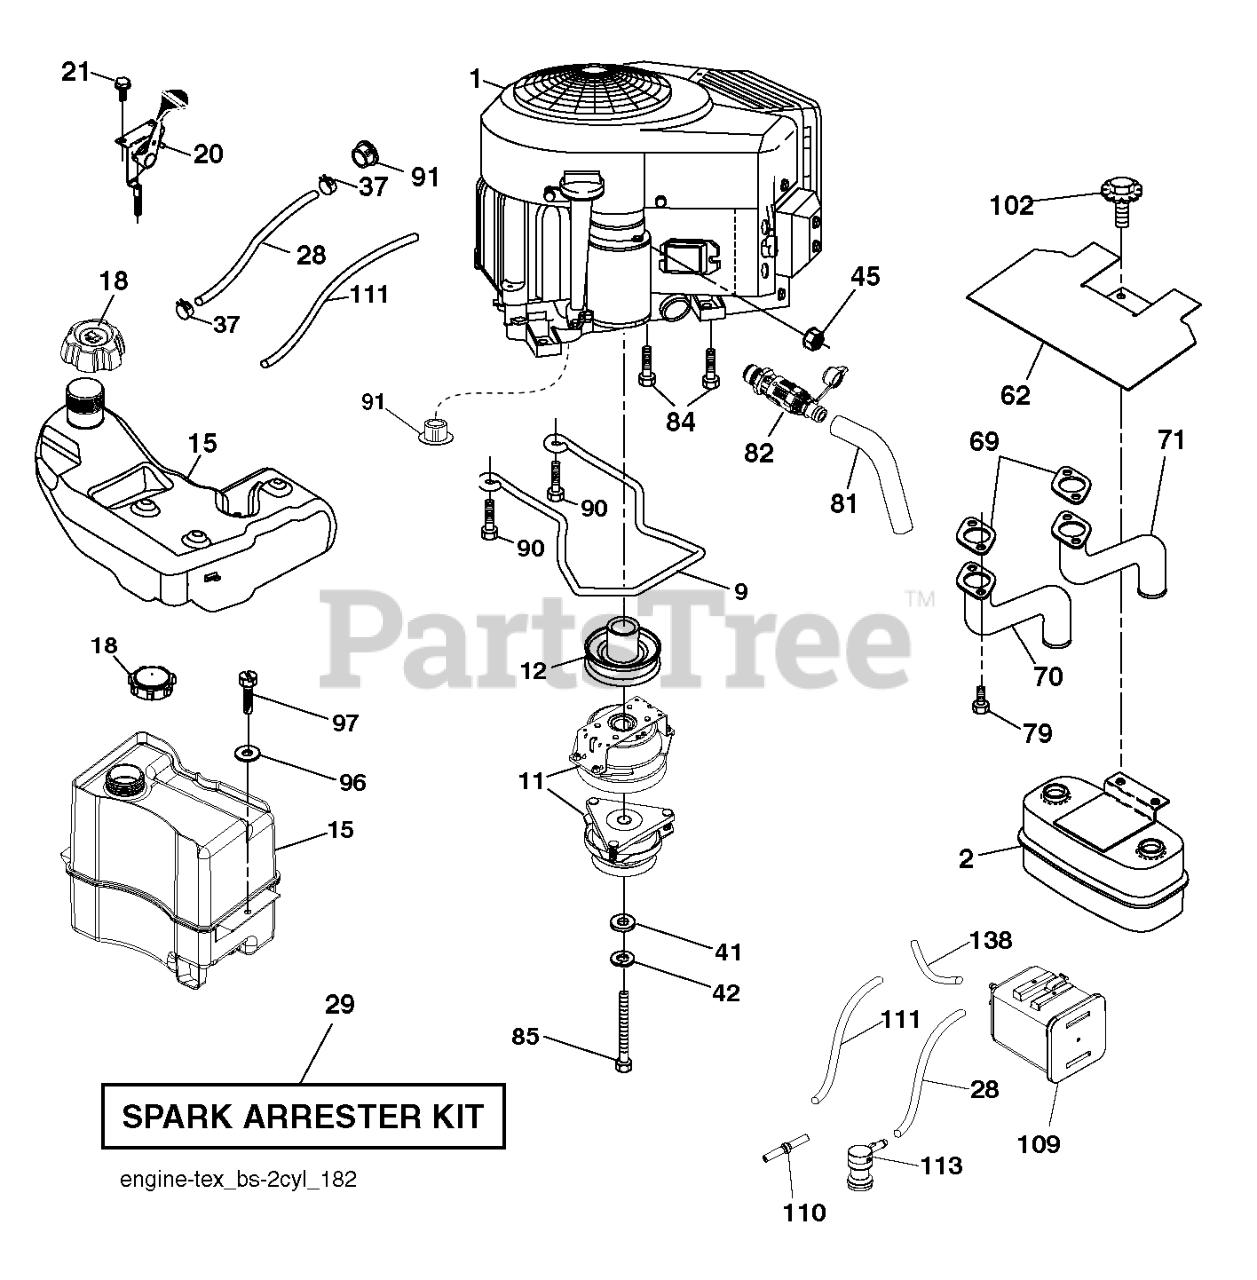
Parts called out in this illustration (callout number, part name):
2	MUFFLER.ASM.TWIN.MNTG.BRACKET
2	MUFFLER.TWIN.CYL.LOW.TONE
9	KEEPER.BELT.ENG.4.25"2.BLT.431
11	CLUTCH.OGURA.5.0PD.GT1.5A-EH07
11	KIT.SVC.CLUTCH.ELECTRIC.
12	PULLEY.ENGINE.TUFFTORQ
15	FUEL TANKS
15	Tanks
15	TANK.ASM.FUEL.3GA.CARB
15	FUEL TANK
18	CAP.ASM.FL.RITCH.3"E10.SYM.498
18	FUEL CAP
18	CAP.2.25'.VENTED.RATCHET.EPA
18	Fuel Caps
18	FUEL.CAP.ASM.2.25TETHRED.RATCH
18	CAP ASM.FUEL.2.25"FR.
18	CAP ASSY FUEL 3" GRAY
20	THROTTLE.COBRA.38"READSTART.BK
20	THROTTLE CABLE
20	CONTROL.TH/CK.COBRA.B&S.TWN.BK
21	SCREW.#10 X 0.750.BOS
28	LINE.FUEL.20"FRONT.EMI
28	LINE.FUEL.64"REAR.EMIS
28	HOSE.1/4".LOW.PERM.FUEL.LN.22"
29	KIT.SPARK ARRESTOR 794945 B&S
37	HOSE CLAMP
42	LOCKWASHER
45	NUT HEX_LRG FLG_1_4-20_LOCK
62	SHIELD.HEAT.MUFFLER
69	GASKET.MUFFLER
70	EXHAUST.TUBE.LH.BS/TWIN
71	EXHAUST.TUBE.RH.B&S.TWIN.INTEK
79	SCREW.SOCKET.HEAD.5/16-18
81	TUBE, DRAIN OIL ASM.
82	VALUE.OIL.DRAIN
84	SCREW.3/8-16
85	BOLT.HEX.7/16-20X3.75.GR5.RED
85	BOLT.HEX.7/16-20X4.GR5.1.5BLUE
85	BOLT HEX 7/16-20 X 3.75 GR. 5
90	SCREW 3/8-16X1
91	BUSHING.1.375OD
96	Washers
97	SCREW HEXWSHR 1/4-20X3/4
102	BOLT.HEX.HD.WASHER.5/16-18X.75
102	SCREW
102	BOLT.5/16-18UNCX3/4 W/SEMS.BLK
109	CANNISTER, CARBON
110	VALVE.ASM.ANTI-SLOSH
111	TUBE.PURGE.FUEL.1875
113	VALVE.SLANT.CARTRDG.90 DEG.TEX
138	PURGE.LINE.36"REAR.CALIFORNIA
